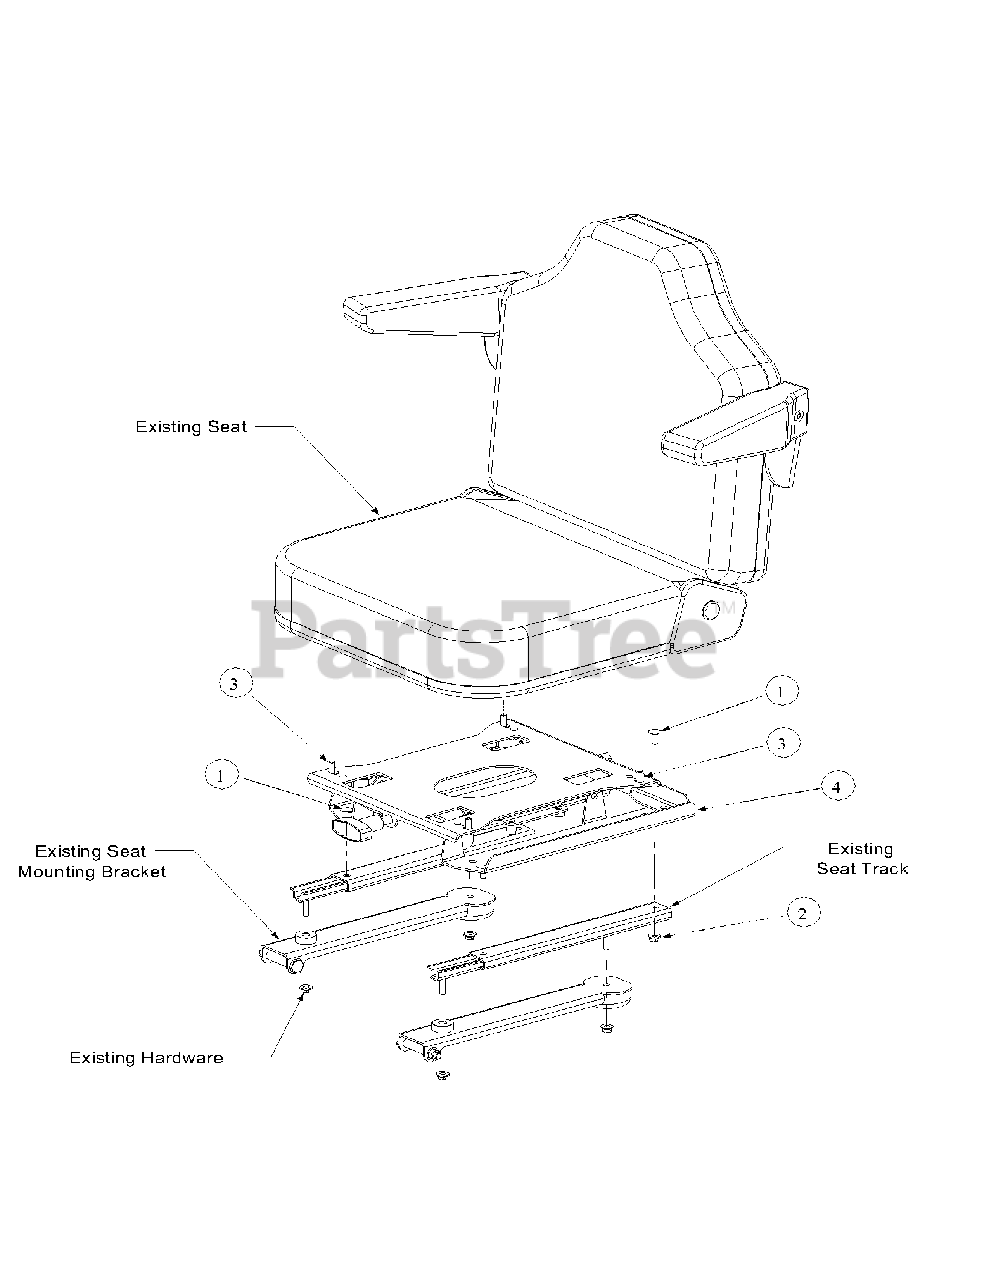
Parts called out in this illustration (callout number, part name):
1	Carriage Bolt, 5/16-18 x .75
2	Nut, Hex Flange Lock, 5/16-18
3	HHCS, 5/16-18 x .75
4	Seat Suspension
